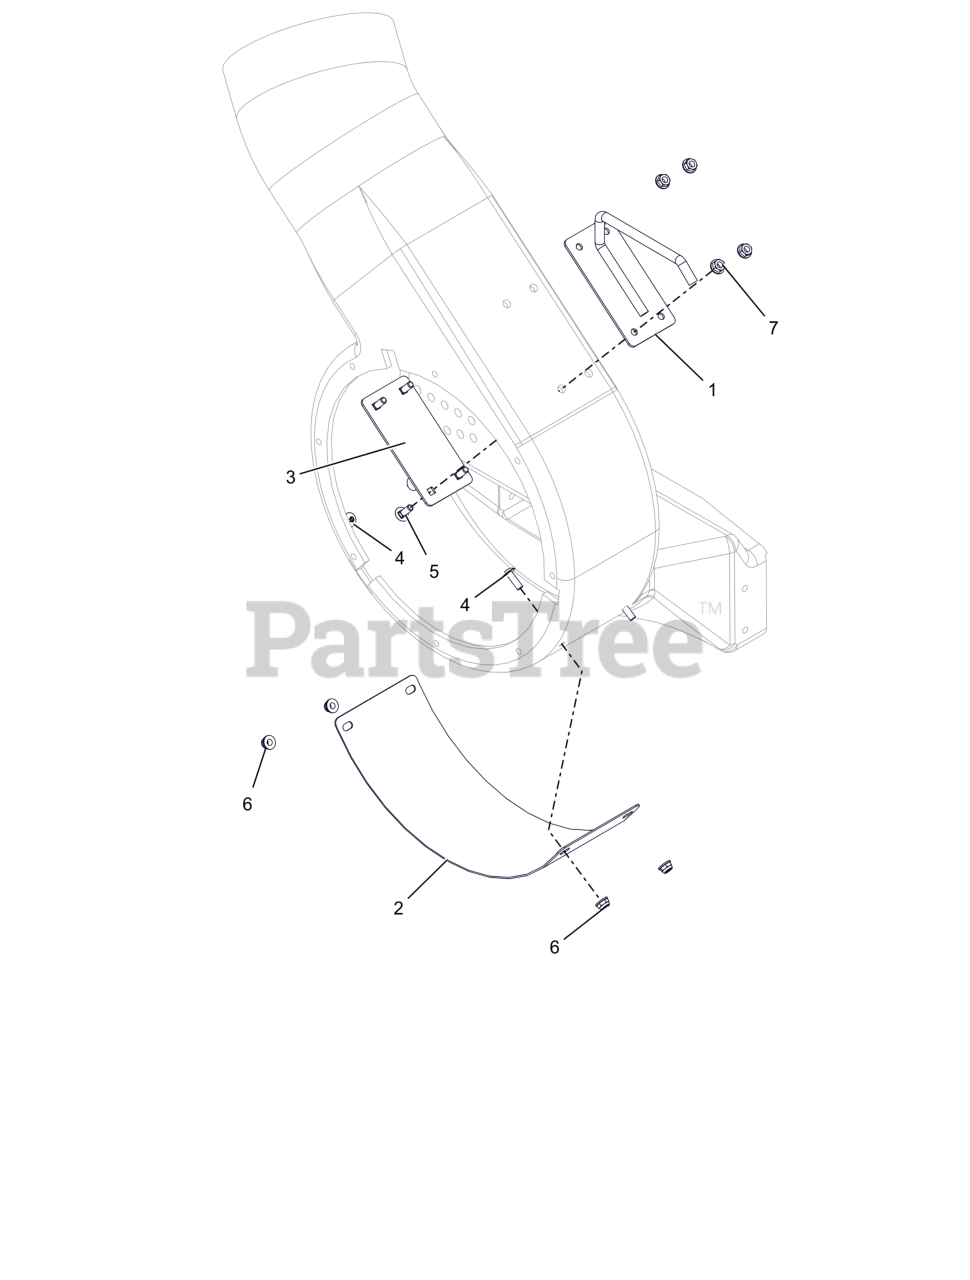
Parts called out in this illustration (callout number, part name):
1	WLDMT, HOUSING HANDLE (BLACK)
2	PLATE, SKID
3	PLATE, HANDLE BACKER (BLACK)
4	SCR-MCH .25-20X.75 TXTR YWZC
5	BLT, RHSN .25-20X.750 G5 ZCC
6	NUT,NYL-FLG .25-20 GF ZCC
7	NUT-LK-CTR-FLG .25-20 ZC120
